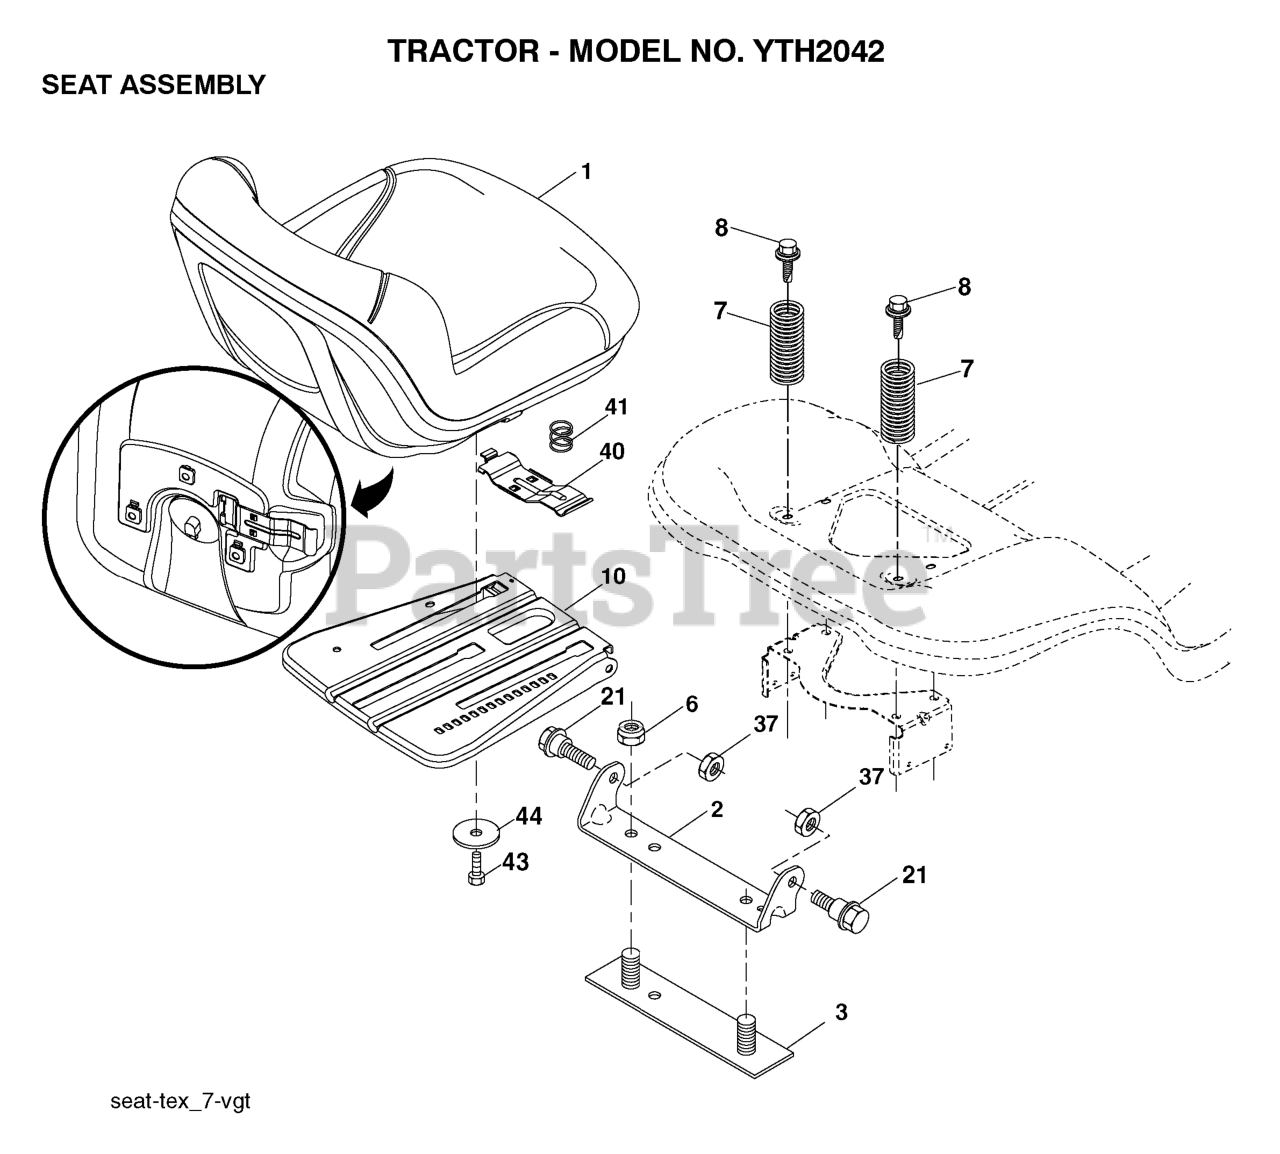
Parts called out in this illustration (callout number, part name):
1	SEAT.TH130.GRY.MILSCO.
2	BRKT.PIVOT.FENDER
3	STRAP
6	NUT
7	SPRING COMPRESSION
8	BOLT.5/16-18UNCX3/4 W/SEMS.BLK
10	PAN.ASM.SEAT.3PT
21	BOLT.SHOULDER.5/16-18
37	NUT.71038.31-18.HEX.NYLOCK
40	HANDLE.SLIDE.SEAT.TEX.BLACK
41	SPRING.LATCH.SEAT.TEX
44	WASHER 13/32 X 2-3/8 X 12GA
